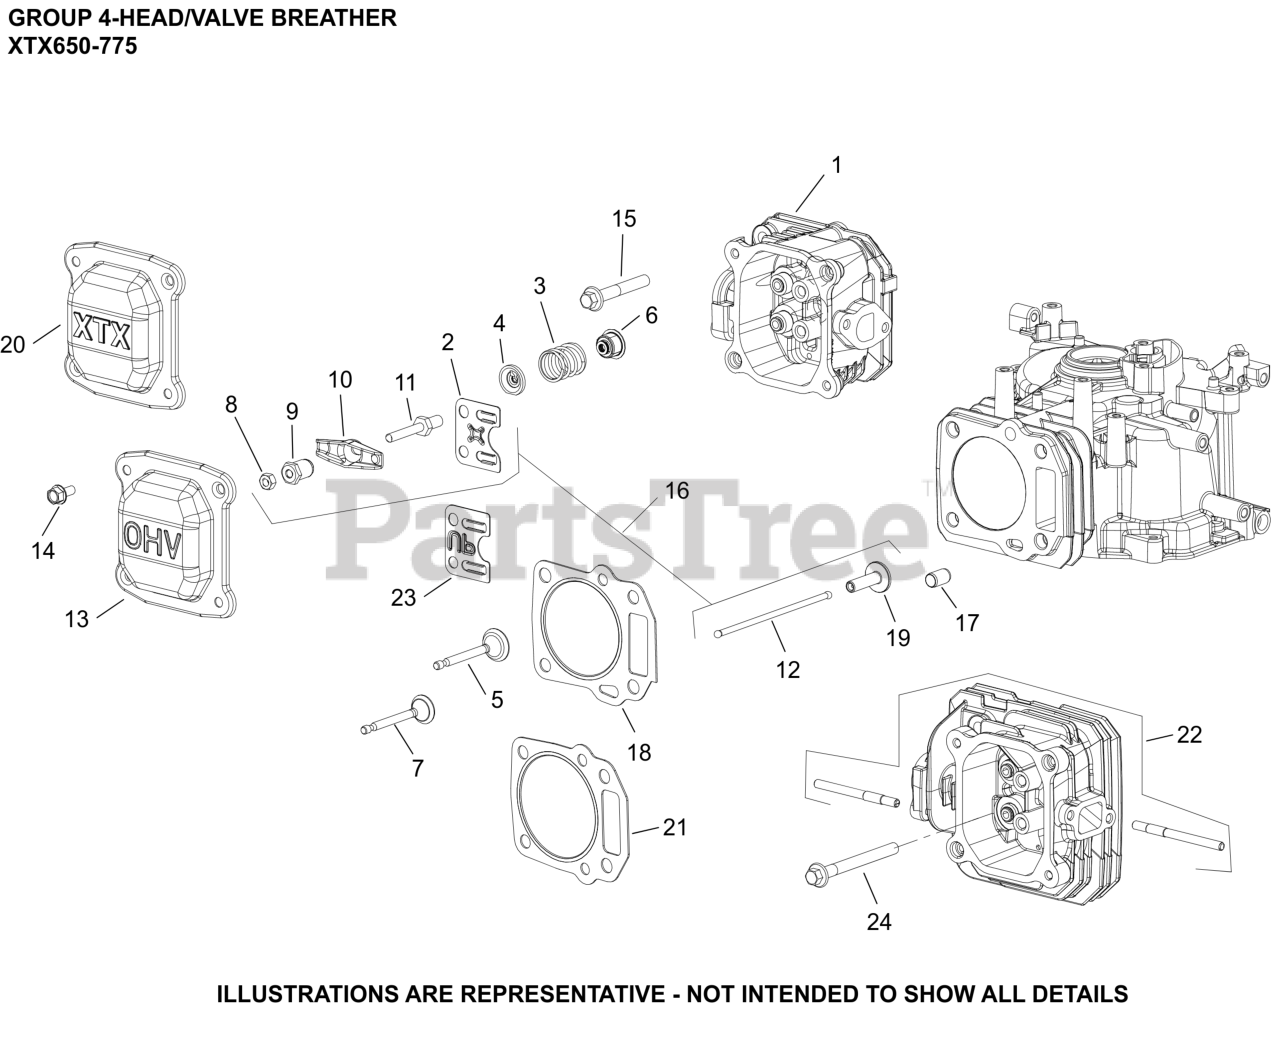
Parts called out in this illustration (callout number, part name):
1	HEAD, CYLINDER
2	PLATE, PUSHROD GUIDE
3	SPRING, VALVE
4	RETAINER, VALVE SPRING
5	VALVE INTAKE
6	SEAL, VALVE STEM
7	VALVE, EXHAUST
8	NUT, HEX JAM
9	PIVOT, ROCKER ARM
10	ARM, ROCKER
11	STUD, ROCKER ARM-USE 14 072 22-S
12	ROD, PUSH
13	COVER, VALVE
15	SCREW, HEX FLANGE M8
17	DOWEL, CYLINDER HEAD
18	KIT HEAD GASKET
19	LIFTER, VALVE
